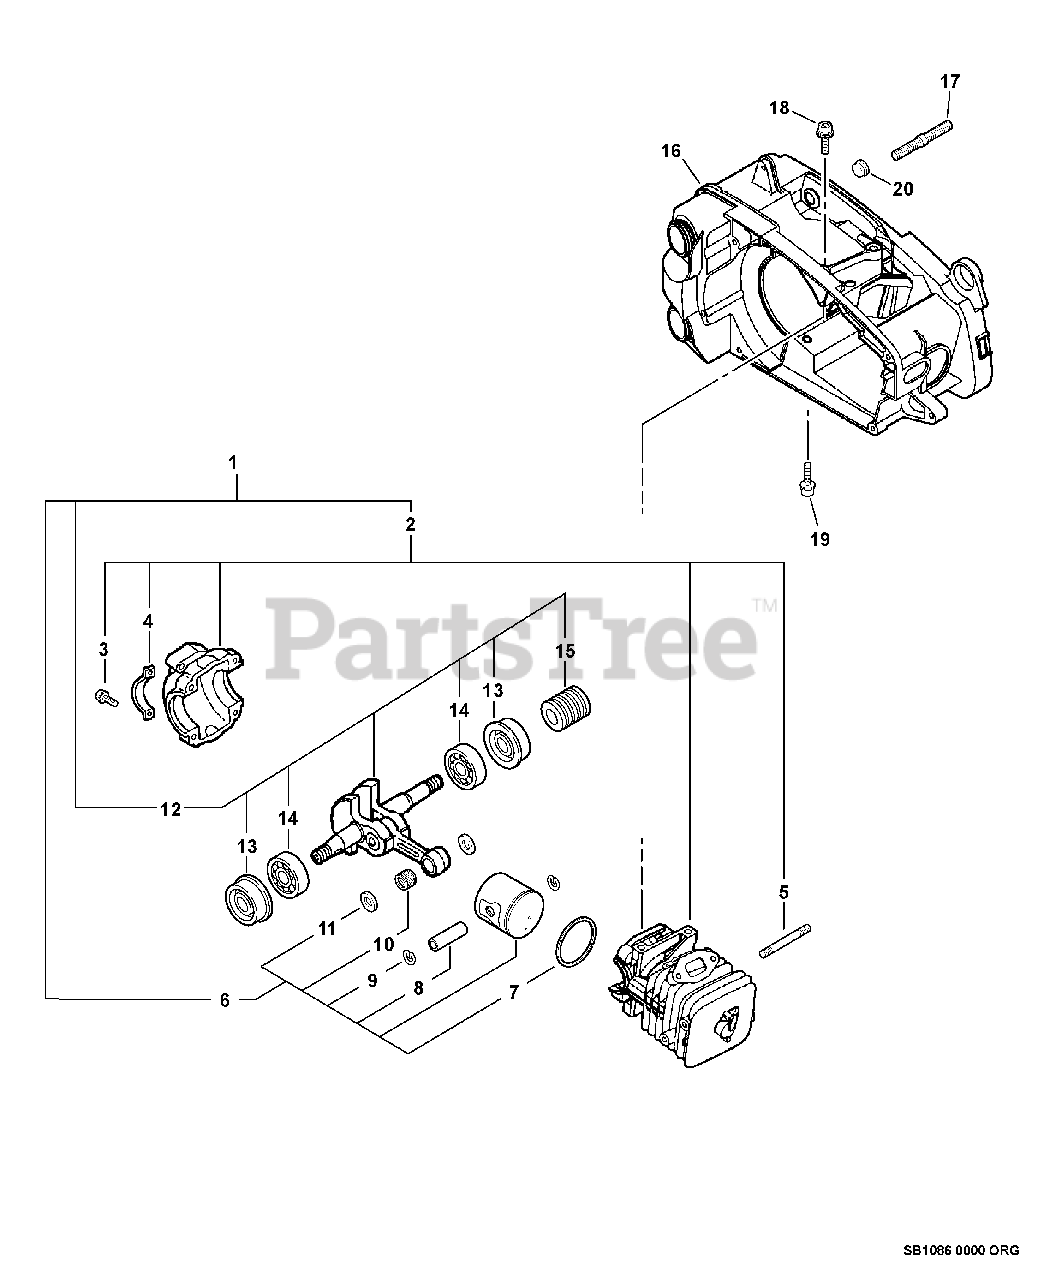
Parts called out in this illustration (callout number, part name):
1	SHORT BLOCK -- SB1086
2	CRANKCASE KIT
3	SCREW - 5X25
4	BRACKET, CRANKCASE
6	PISTON KIT
7	RING, PISTON
8	PIN, PISTON
9	RING, RETAINING
10	BEARING, NEEDLE - 8
11	SPACER, PISTON
12	CRANKSHAFT ASSY
13	SEAL, OIL - 12
14	BEARING, BALL - 6201
15	GEAR - WORM
16	COVER, ENGINE - ORANGE
17	STUD, GUIDE BAR
18	SCREW - 5X20
19	SCREW - 5X30
